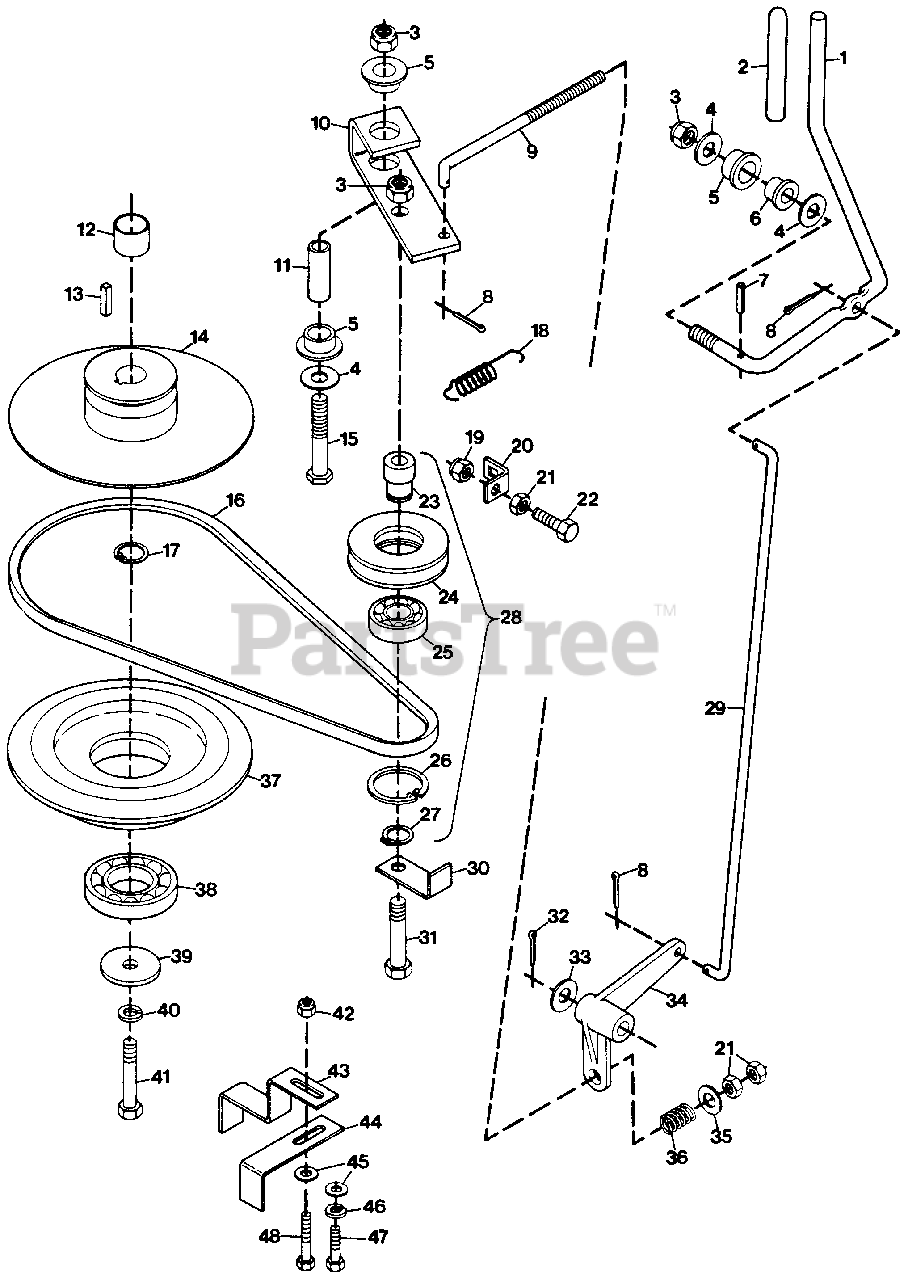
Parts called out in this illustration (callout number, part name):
1	LEVER, PTO ACTUATING
2	GRIP, PTO LEVER
3	NUT, LOCK 1/2-13
4	WASHER, FLAT .531X1.250X.100
5	BUSHING, NYLON .76X1X.6 FLANGE
6	BUSHING, .513X.750X.625
7	PIN, SPRING .187X1.000
8	PIN, COTTER .09X.75
9	ROD, PTO CLUTCH ACTUATING
10	ARM, IDLER PIVOT
11	SPACER
12	SPACER, ELECTRIC CLUTCH
13	KEY, SQUARE .250X1.250
14	HUB, PTO AND DRIVE CLUTCH
15	BOLT, HEX 1/2-13X2.75 SPECIAL
16	V-BELT, PTO CLUTCH
17	RING, RETAINING
18	SPRING, PTO RETURN
19	NUT, LOCK 3/8-16
20	TAB, SPRING
21	NUT, HEX 3/8-16
22	BOLT, HEX 3/8-16X1.50
23	BUSHING
24	SHEAVE, IDLER
25	BEARING, BALL
26	RING, RETAINING
27	RING, RETAINING
28	ASSEMBLY, IDLER SHEAVE
29	ROD, PTO CONTROL
30	GUIDE, BELT
31	BOLT, HEX 1/2-13X2.50
32	PIN, COTTER .125X.75
33	WASHER, FLAT .531X1.062X.095
34	LEVER, PTO CLUTCH
35	WASHER, FLAT .406X.812X.065
36	SPRING, COMP. 1X.78X338
37	SHEAVE, MOWER CLUTCH
38	BEARING, BALL 1.574X3.149X.708
39	WASHER, SPECIAL
40	WASHER, LOCK 7/16 REG.
41	BOLT, HEX 10MMX1.5
42	NUT, LOCK 5/16-18
43	GUIDE, PTO V-BELT
44	GUIDE, V-BELT
45	WASHER, FLAT .344X.688X.065
48	BOLT, HEX 5/16-18X1.75
